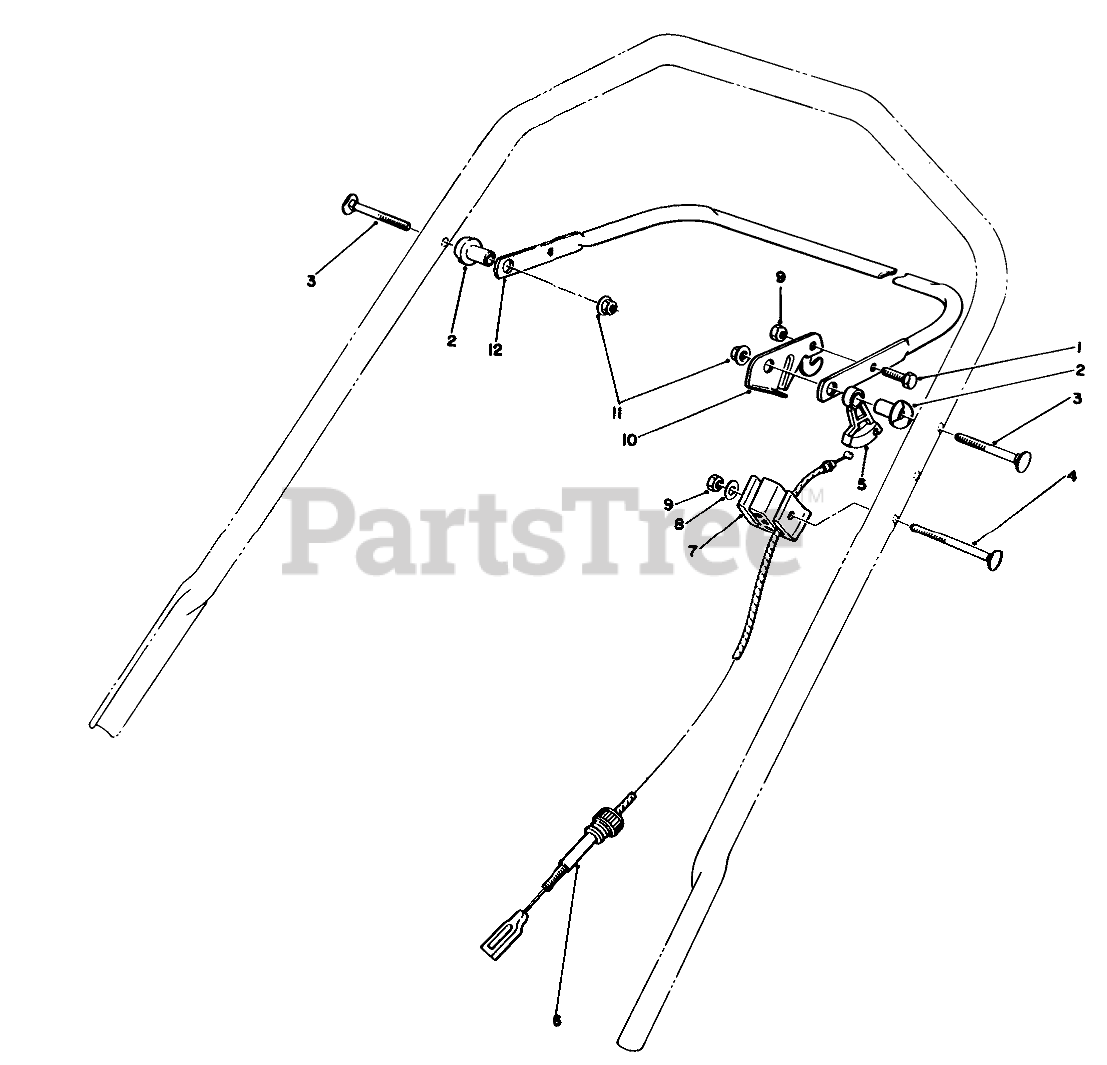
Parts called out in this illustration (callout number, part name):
1	SCREW-HH
2	SPACER-SUPPORT
3	5/16-18 X 2 HNDLE SCREW
4	HANDLE SCREW
5	LEVER-TRACTION
6	CABLE-TRACTION
7	SUPPORT-CABLE
8	WASHER-FLAT
9	NUT-LOCK, NI
10	CONTROL LEVER
11	NUT-LOCK, NI
12	Bar-Control
